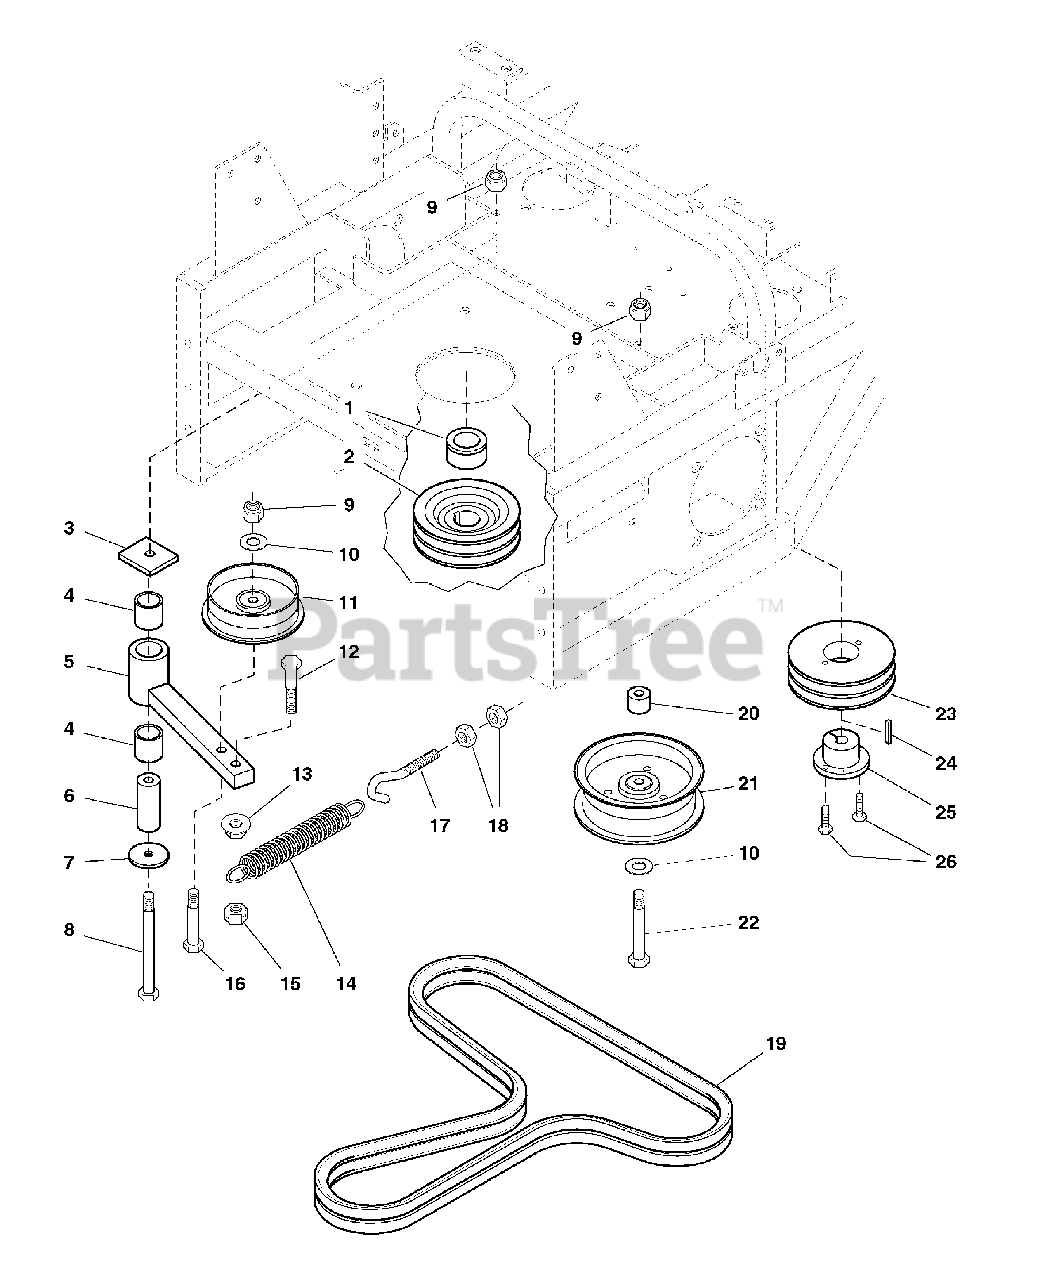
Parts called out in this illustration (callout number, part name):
1	CRANKSHAFT SPACER
2	CRANKSHAFT PULLEY
3	SPACER, Idler Pivot
4	BUSHING, Brass
5	PUMP DRIVE IDLER ARM
6	SHAFT, Idler Pivot
7	RETAINER, Idler Arm
8	CAPSCREW, Hex Hd, 3/8-16 x 4
9	NUT, Hex, Nylon Lock, 3/8-16
10	WASHER, 3/8
11	PULLEY, Idler (Single Flange)
12	CAPSCREW, Hex Hd, 3/8-16 x 1-3/4
13	NUT, Hex, Serrated Flange, 3/8-16
14	SPRING, Extension (48" Model - SN: 101-425)(52: Model - SN: 101-350)
14	SPRING, Extension (48" Model - SN: 426 & up)(52: Model - SN: 351 & up)
15	NUT, Hex, Side Lock, 3/8-16
16	CAPSCREW, Hex Hd, 3/8-16 x 2-1/4
17	SCREW HOOK, 3/8-16 x 4-1/4
18	NUT, Hex, 3/8-16
19	BELT, BANDED A-SEC, 64.76EL, POLY, RAW EDGE
20	SPACER, Idler
21	PULLEY, Idler
22	CAPSCREW, Hex Hd, 3/8-16 x 2-3/4
23	PULLEY, Pump Drive
24	KEY, 5mm x 25mm
25	BUSHING, Tapered Hub
26	BOLT, 1/4-20 X 1", GD
